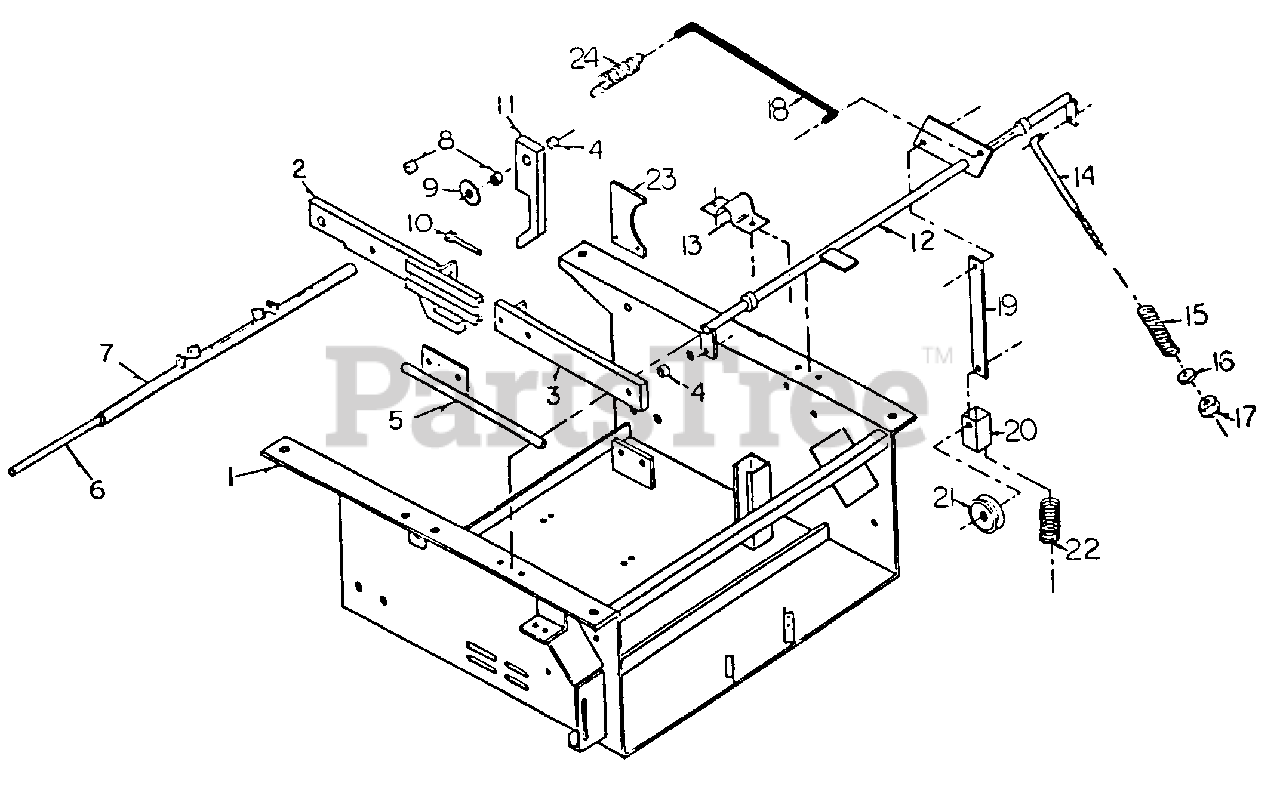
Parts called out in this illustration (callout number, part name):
1	Base
2	RH Deck Lift Arm, Front RH
3	Deck Lift Arm, Back
4	Bushing, Short
6	Cross Bar Pin
8	Bushing, Long
9	Body Mount Washer
10	Tap Bolt, 3/8-16 x 3", GR5
11	Forward Nose Down Lock
12	Brake Clutch Cross Rod
13	Bearlng, Brake Crosg Rod
15	Callper Spring
16	Flatwasher, 1/4"
17	Elastic Stop Nut, 1/4-20
18	Brake Pedal Rod
19	Cross Rod to Idler Pulley Linkage
20	Sprlng Loaded ldler Mount
21	Idler Pulley
24	Brake Pedal Spring
